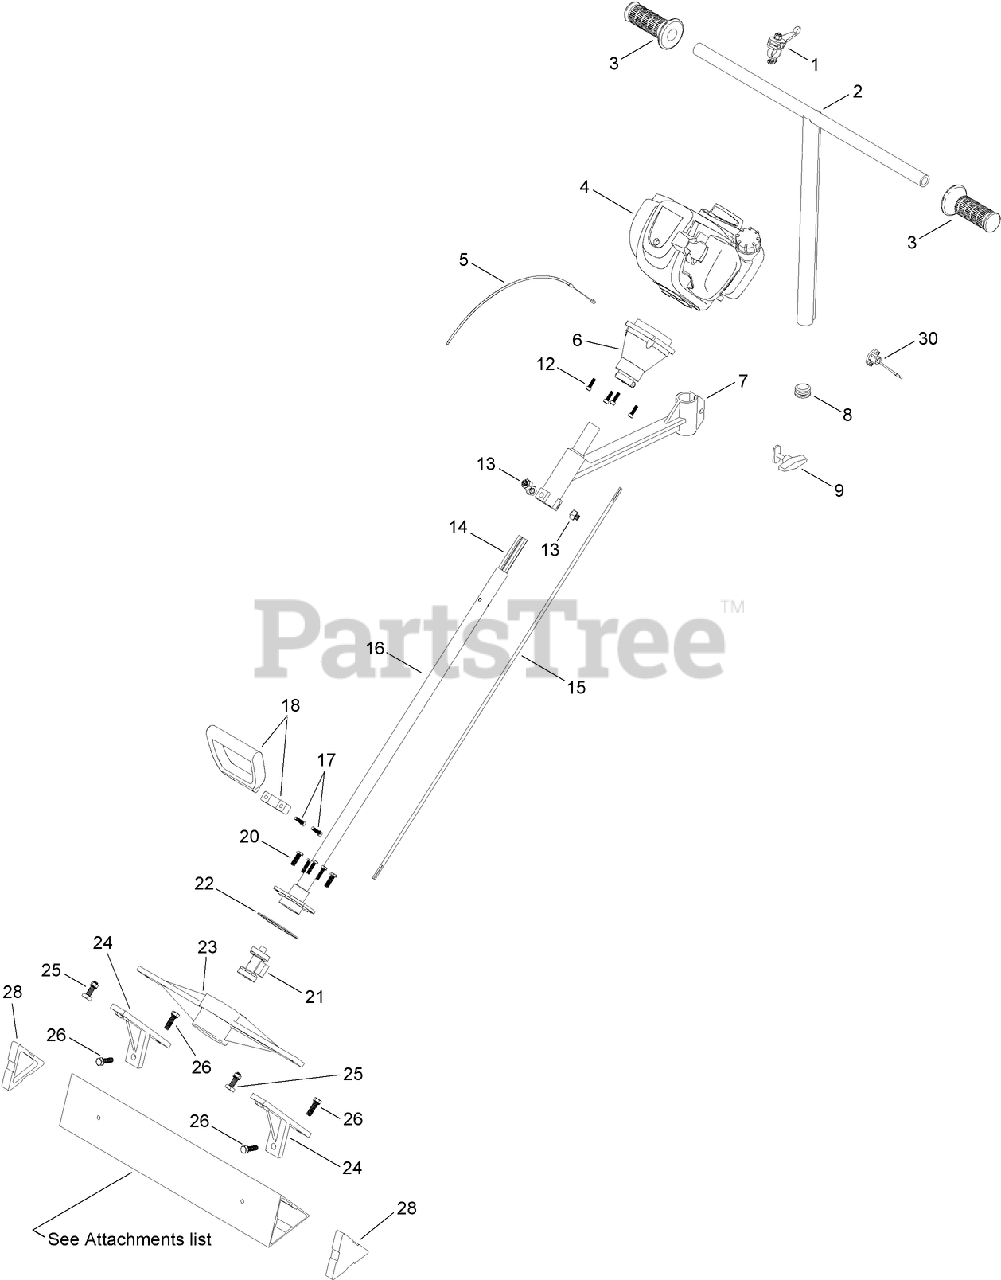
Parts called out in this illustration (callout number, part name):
1	THROTTLE LEVER ASM
2	T BAR ASM
3	GRIP-T BAR
4	ENGINE-HONDA
5	CABLE-THROTTLE
6	CLUTCH
7	MOUNT-UPPER
8	PLUG-CAP, T BAR
9	KNOB ASM
12	SCREW-HH
13	SET SCREW ASM (W/JAM NUTS)
14	LINER-STAR
15	SHAFT-DRIVE, FLEX
16	TUBE-OUTER (W/RACE)
17	SCREW-HSH
18	GRIP HANDLE ASM
20	SCREW-HH
21	WEIGHT AND SHAFT ASM
22	GASKET-OIL
23	LOWER CASTING ASM
24	CLAMP-SADDLE
25	BAR BOLT ASM (SADDLE CLAMP)
28	CAP-END, BAR
30	KILL SWITCH ASM
